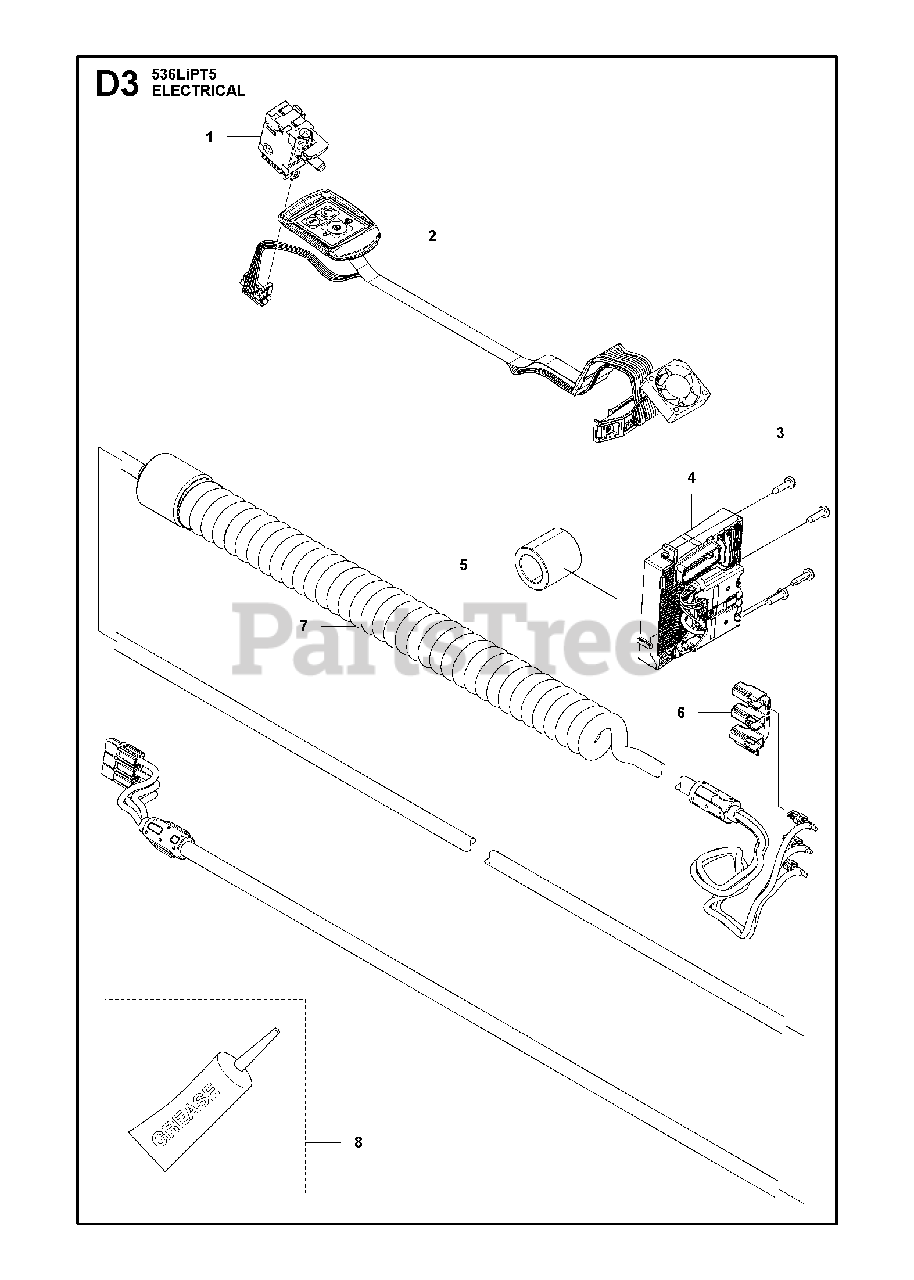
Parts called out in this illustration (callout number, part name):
1	TRIGGER SWITCH
2	WIRING ASSY POLE SAW
4	CONTROL UNIT
5	HOUSING POWER TIMER 3
6	FERRITE CORE
7	WIRING ASSY TELESCOPI
8	GREASE TUBE Q8 RUYSDAEL WR2
